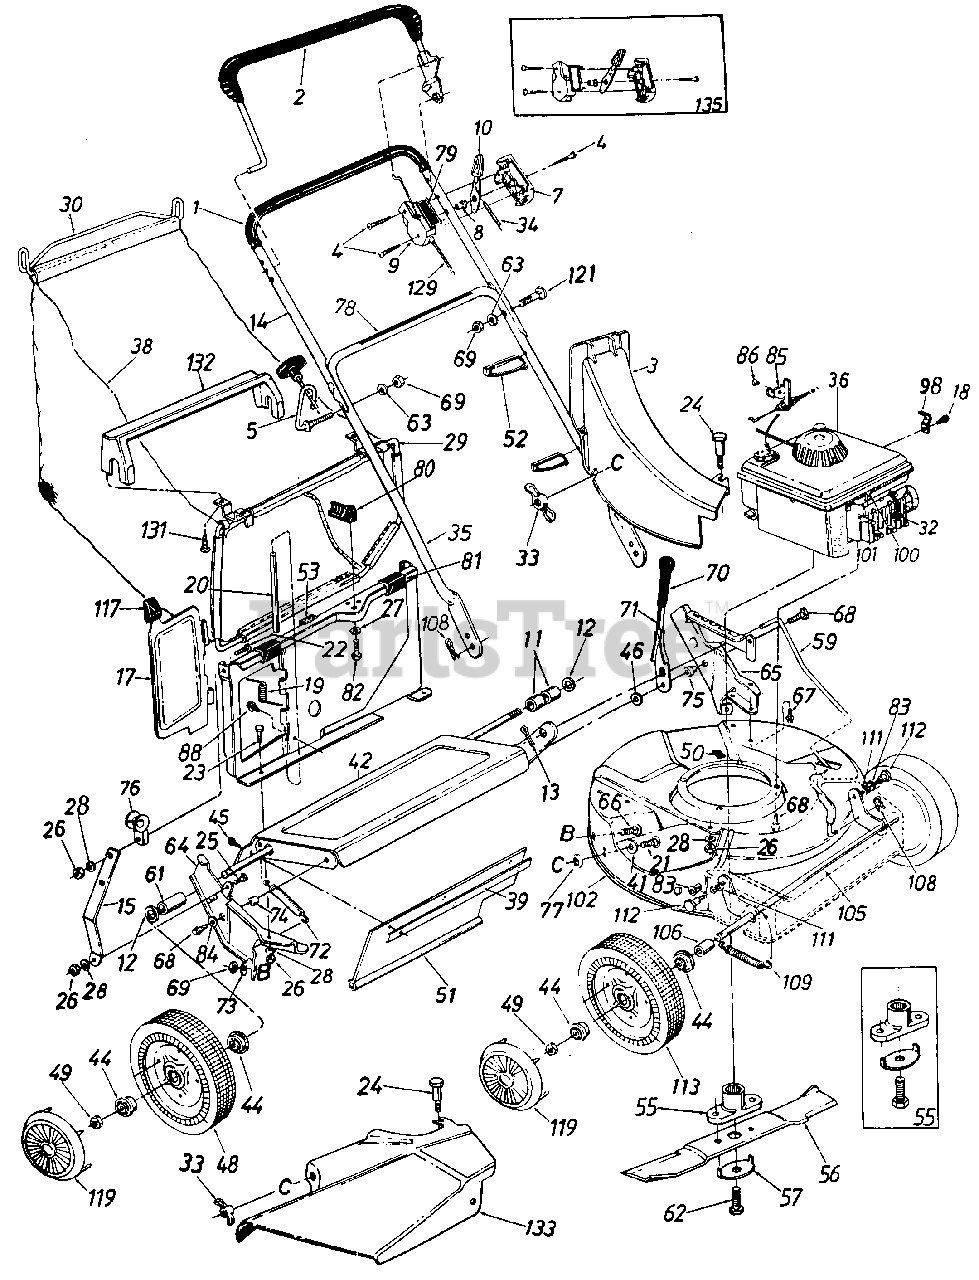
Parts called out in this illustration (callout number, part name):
1	GRIP-SHRINK-25 IN
3	CHUTE ASSY-TOP DISCH
4	SCREW-TRUSS MACH
5	SCREW-RECOIL HANDLE GUIDE
7	PANEL HALF-CONTROL
8	PIN-CONTROL DISC
9	PANEL HALF-CLUTCH
10	LEVER-THROTTLE CONT-REV
12	WASHER-FL-.510 ID X .75 OD X .033
13	PIN-COTTER-3/32 DIA X .75
14	HANDLE-UPPER-CHROME
15	BRACKET-PANEL SUP
17	DOOR-TOP DISCHARGE
18	SCREW-HEX B-TAP #10 X .38
19	SPRING-TORSION
21	BOLT-CARRIAGE 1/4-20 X .62
22	SCREW-TRUSS MACH
23	SCREW-HEX 1/4-20 X .50
24	SCREW-SHLD
25	SCREW-HEX 1/4-20 C .62
26	NUT-HEX 1/4-20
27	WASHER-SHAKE PROOF
28	LOCK WASHER 1/4 DIA
29	FRAME-GRASSCATCHER
30	HANDLE-GRASSCATCHER
32	INSULATOR-SPARK PLUG
33	NUT-WING
34	WIRE-THROTTLE 58 LG
35	HANDLE-LOWER PAINTED
38	BAG-GRASS-CONV
39	STRIP-RETAINING
41	WASHER-FL-.344 ID X .62 OD X .033
42	AXLE-RR-PUSH ASSY
44	BEARING-BALL
45	SCREW-HEX WASH HD
46	WASHER-FL-.385 X 1.00 X .135
48	WHEEL ASSY W/TIRE
49	NUT-HEX INS L-1/2-20
52	TIE-CABLE
53	STRIP-FOAM 1/4X1.0
55	KIT-BLADE ADAPTER-SPLINED
56	BLADE-21IN
57	KIT-BLADE MOUNTING
59	ROD-HGT ADJ 1.50 X 19.42
62	SCREW-HEX 7/16-20 X 1.50
63	WASHER-LOCK-5/16
64	BRACKET ASSY-HDLE-RH
65	BRACKET ASSY-HDLE-LH
66	BOLT-CARRIAGE 5/16-18 X .62
67	SCREW-HEX WASH HD 5/16-18X1/2
68	SCREW-HEX
69	NUT-HEX 5/16-18
71	LEVER-HGT ADJ
72	SPRING-EXTENSION
73	WASHER-BELL .337 X .867 X .057
75	SPACER-SHLD .500 X .100
76	GUIDE-ROPE
77	RETAINER-BOLT 1/4X.50 OD
80	KNOB-LOCKING
81	CLIP-PANEL BAG
82	SCREW-HEX WASH 1/4-20X.75
83	BEARING-NYLINER
84	WASHER-FL-.531 ID X 1.25 OD X 1.00
85	BRACKET-CABLE
88	SCREW-HEX B-TAP #10 X .38
98	CLAMP-CASING
100	SCREW-HEX WASH HD TAP
101	CLIP-CASING
102	DECK ASSEMBLY-20IN-TOP
105	AXLE ASSY-FR-290
108	PIN-INTERN COT-5/16 DIA
109	SPRING-EXTENSION
111	WASHER-INTERN L 3/8 X.56 OD X .018
112	SCREW-SHLD
113	WHEEL ASSY W/TIRE 7X1.75BB
117	KNOB
119	HUB CAP
121	BOLT-CARRIAGE-CURV 5/16-18 X 1.38
129	CABLE-CONTROL
131	SCREW-TAP .215 X 1
132	HANDLE-BAG-BLACK
133	DEFLECTOR-CHUTE
135	KIT-THROTTLE CONTROL
